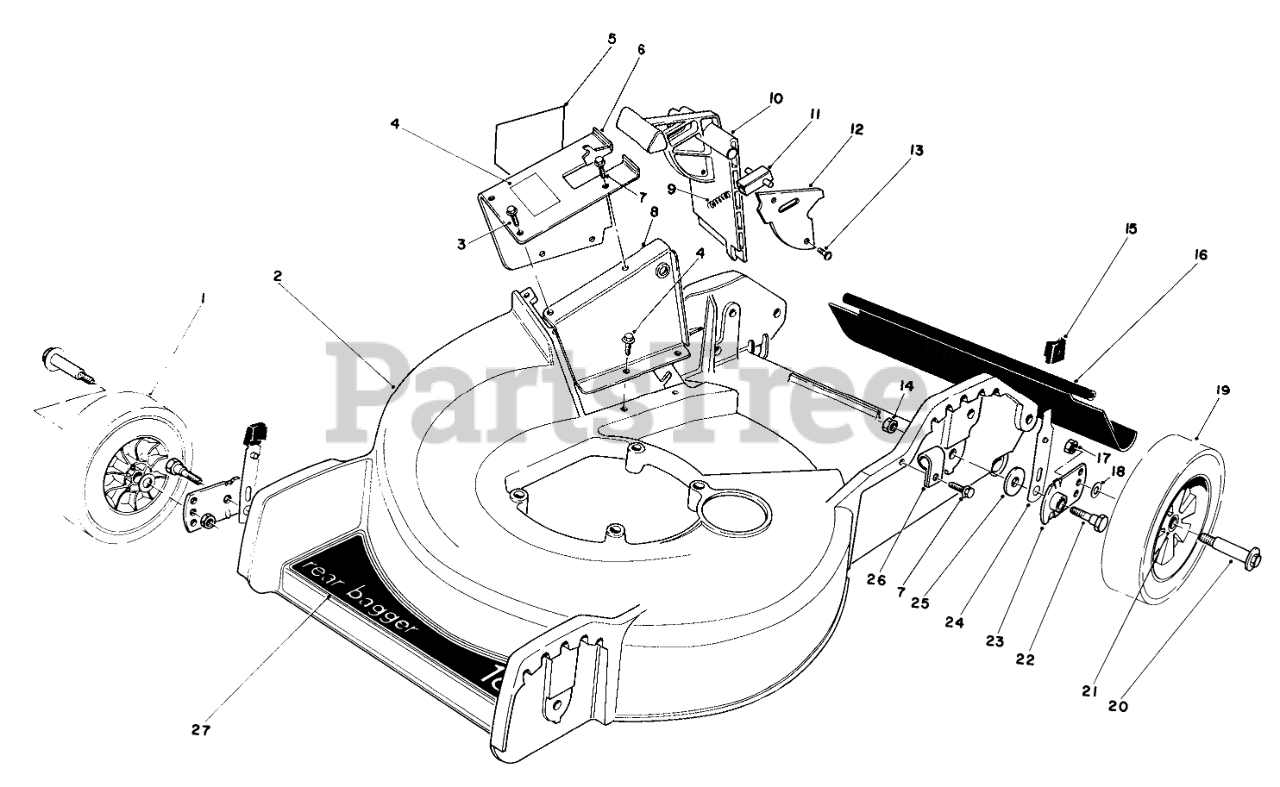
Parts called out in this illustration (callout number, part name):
1	Wheel & Tire Assembly (Incl. Ref. #20)
2	Housing
3	SCREW
4	Decal-Door
5	DECAL-DANGER
6	Tunnel-Outer
7	SCREW
8	Tunnel-Inner
9	SPRING-COMPRESSION, LATCH
10	Door Mulching
11	Door Latch
12	Cover Door
14	NUT-LOCK, NI
15	KNOB-ARM
16	SHIELD - TRAILING
17	Nut
18	WASHER
19	Wheel & Tire Assembly (Incl. Ref. #20)
20	BOLT-WHEEL
21	BUSHING
22	PIVOT SCREW
23	PIVOT ARM ASSY
24	SPRING ARM ASM
25	PIVOT WASHER
26	CLAMP-NYLON
27	DECAL-DECK
